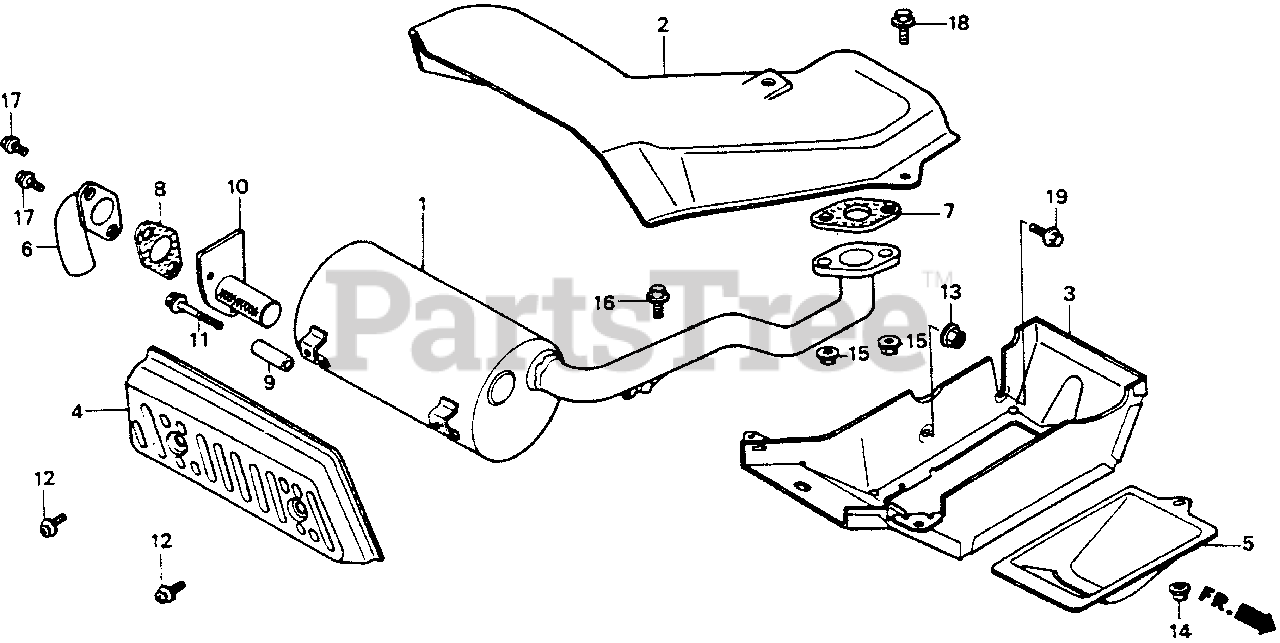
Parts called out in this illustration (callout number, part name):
1	MUFFLER (NOT AVAILABLE)
2	PROTECTOR, HEAT (UPPER)
3	PROTECTOR, HEAT (LOWER)
4	PROTECTOR, MUFFLER
5	COVER, PROTECTOR (LOWER)
6	PIPE, TAIL
7	GASKET, EX. PIPE
8	GASKET, TAIL PIPE
9	COLLAR, MUFFLER JOINT
10	ARRESTER, SPARK
11	BOLT, FLANGE (8X55)
12	SCREW-WASHER (6X10)
13	NUT, FLANGE (6MM)
14	NUT, FLANGE (6MM)
15	NUT, FLANGE (8MM)
16	BOLT, FLANGE (6X10)
17	BOLT, FLANGE (6X10)
18	BOLT, FLANGE (6X12)
19	BOLT, FLANGE (6X16)
